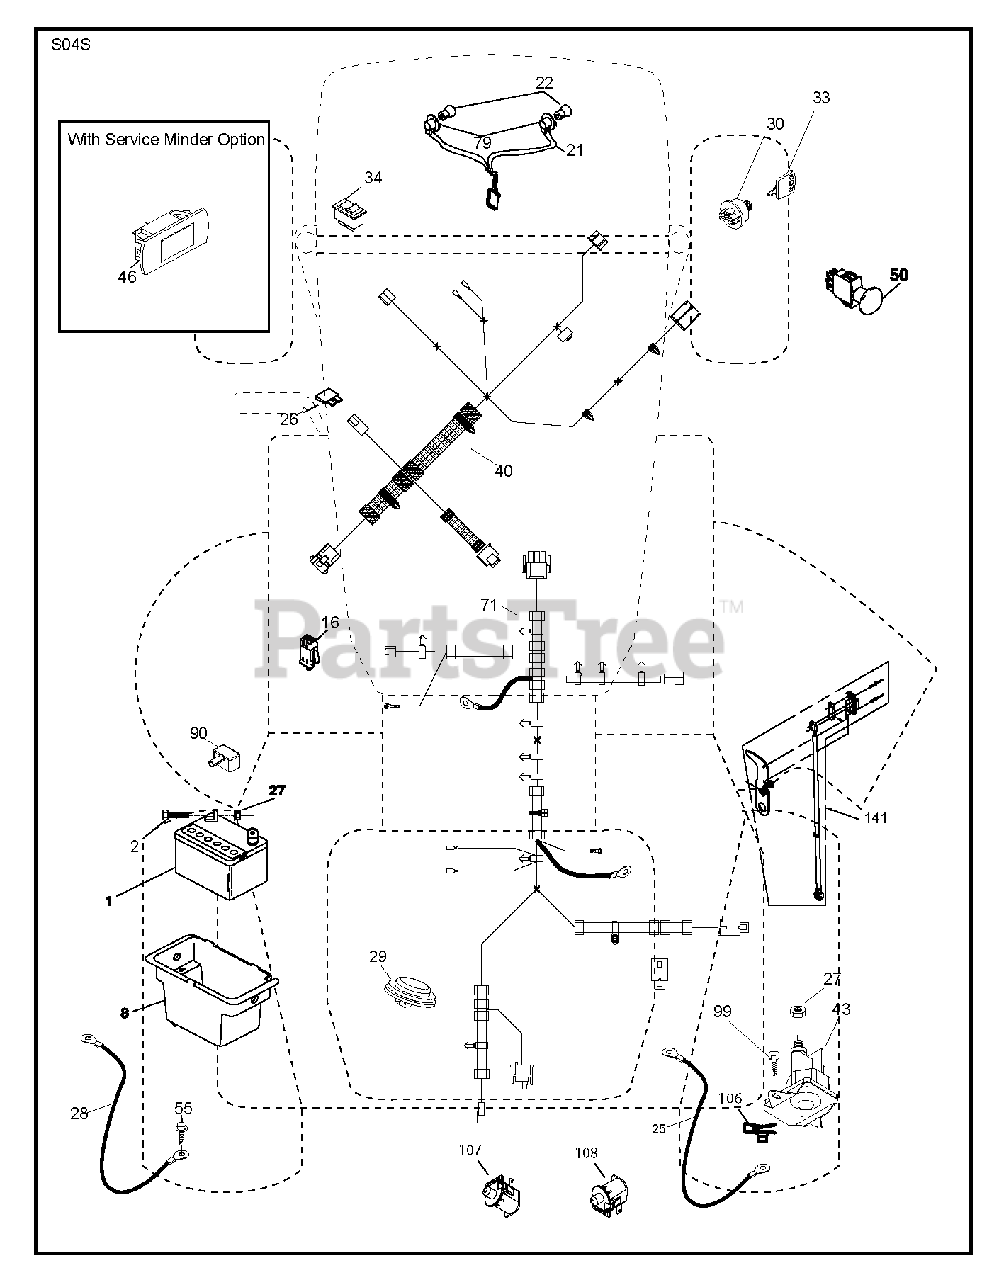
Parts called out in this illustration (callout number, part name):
1	Battery, Dry 30 Amp
2	BOLT.HEX.1/4.X.3/4.DICHROMATE
8	BOX.BATTERY.LT/SRD
16	SWITCH INTERLOOK PUSH-IN
21	HARNESS.LIGHT W/4152J BULBS
25	CABLE.BATTERY.20.RED.8 AWG
26	FUSE 20AMP
27	NUT
28	CABLE.GROUND.REAR.BATTERY.8G
29	SWITCH.SEAT.DELTA.OPC.
30	SWITCH.IGN.DELTA.W.LGH.ROS
33	KEY.CHAIN.BLISTER.PACK.GEN.INT
40	WIRING HARNESS
43	SOLENOID.W/BRASS.PLUNGER
46	RP GUAGE.SRVCMNDR.HRMTR.
50	RB PTO.SWITCH.8 TERMINAL.BLACK
55	SCREW 5/16"
71	RP HARNESS.ELEC.CHASSIS.SRD
79	BULB HOLDER ASM.
90	COVER.TERMINAL.BATTERY
99	SCREW HEXWSHR 1/4-20X3/4
106	1/4-20 U NUT
107	SWITCH.SNAPMOUNT.NO.#2
108	SWITCH.SNAPMOUNT.NC
141	KIT T2.ROS 71677
